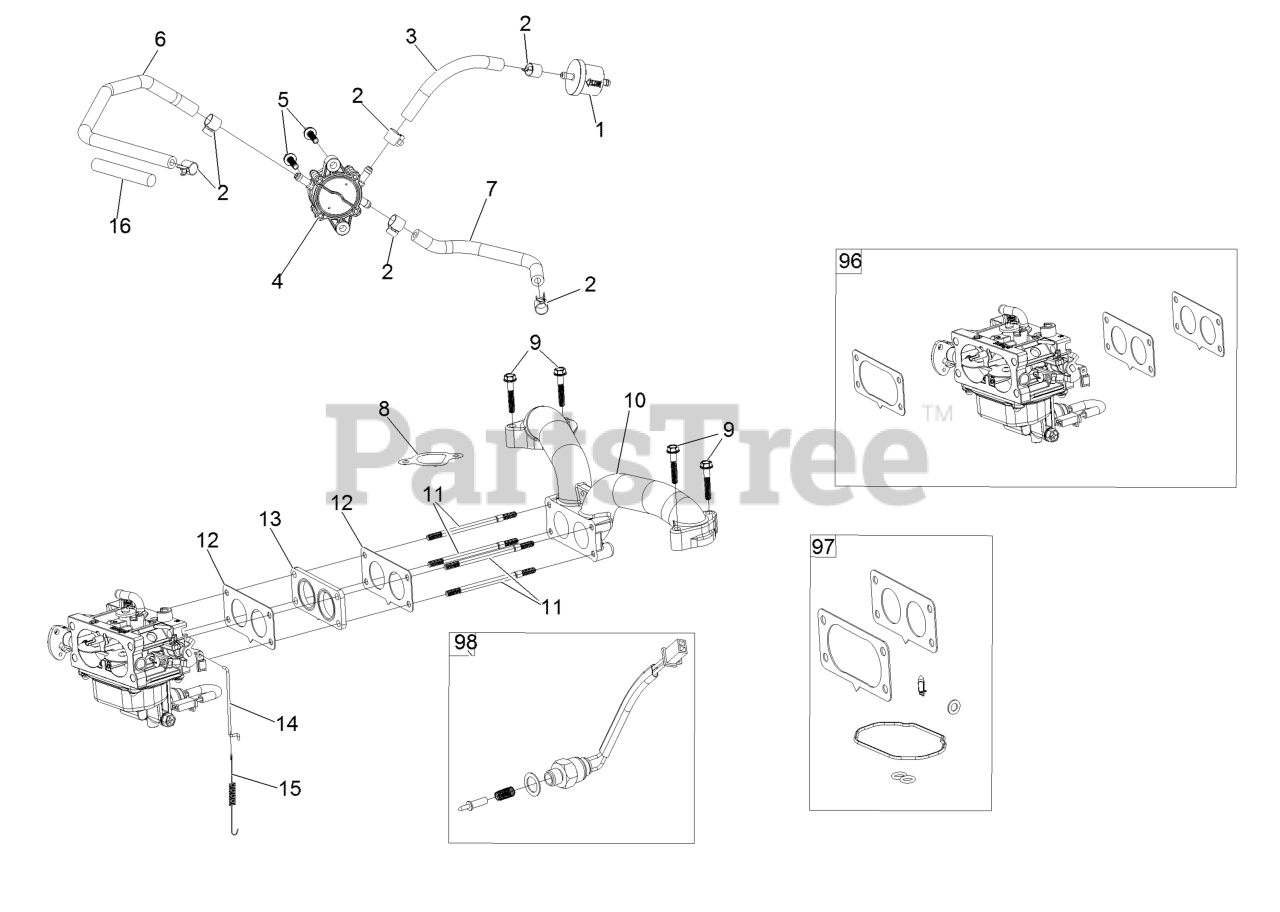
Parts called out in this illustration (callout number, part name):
1	Filter-Fuel
2	Clamp-Fuel Line
3	Line-Fuel
4	Pump-Fuel
5	Screw-HHF
6	Hose-Fuel
7	Hose-Fuel
8	Gasket-Intake
9	Screw-HHF
10	Manifold-Intake
12	Gasket-Carburetor
13	Insulator-Carburetor
14	Linkage-Throttle
15	Spring-Return, Throttle
16	Sleeve-Fuel Line Protector
96	Carburetor Replacement Kit ASM
97	Carburetor Repair Kit
98	Solenoid Kit
99	High Altitude Kit
